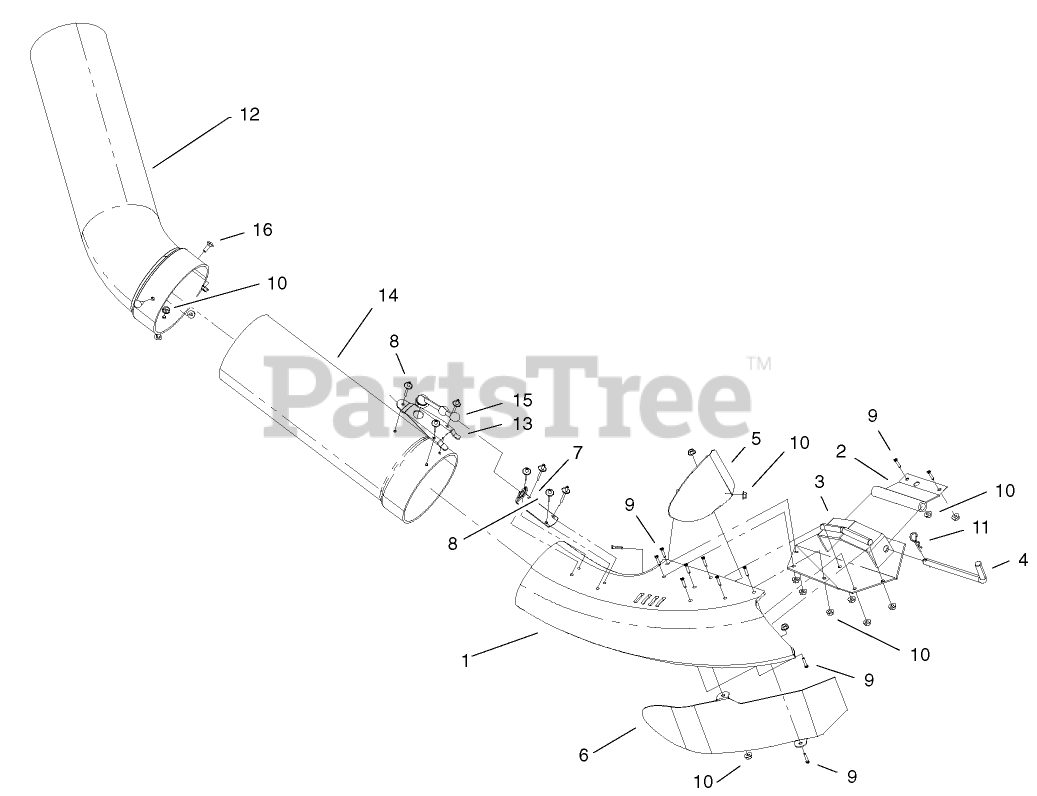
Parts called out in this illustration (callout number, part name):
2	BRACKET-DECK
3	BRACKET-BOOT
4	PIN-BOOT
5	BAFFLE
6	BAFFLE
7	BRACKET-LATCH
8	RIVET-POP
10	NUT-HF
11	HAIRPIN
12	TUBE-ELBOW
13	BRACKET
14	TUBE-STRAIGHT
15	LATCH-RUBBER
16	BOLT-CARR
